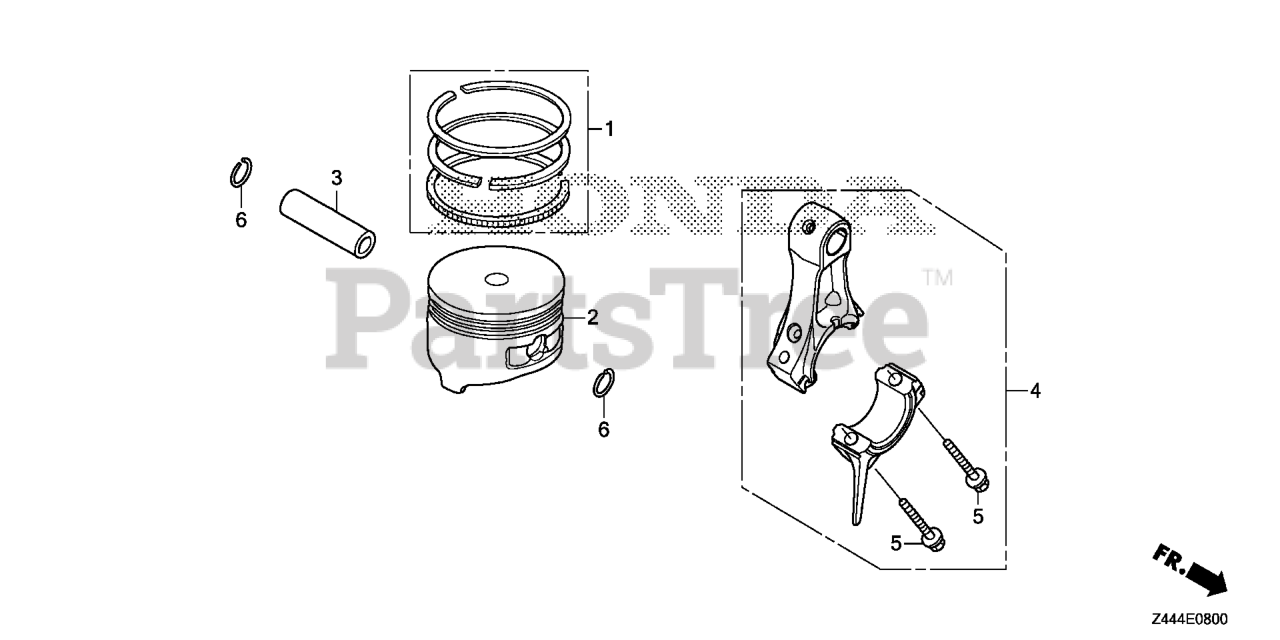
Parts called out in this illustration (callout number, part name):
1	RING SET, PISTON (STD) (NIPPON)
3	PIN, PISTON
4	ROD ASSY., CONNECTING
4	CONN ROD ASSY.
5	BOLT, CONNECTING ROD (6X32)
6	CLIP, PISTON PIN (13MM)
